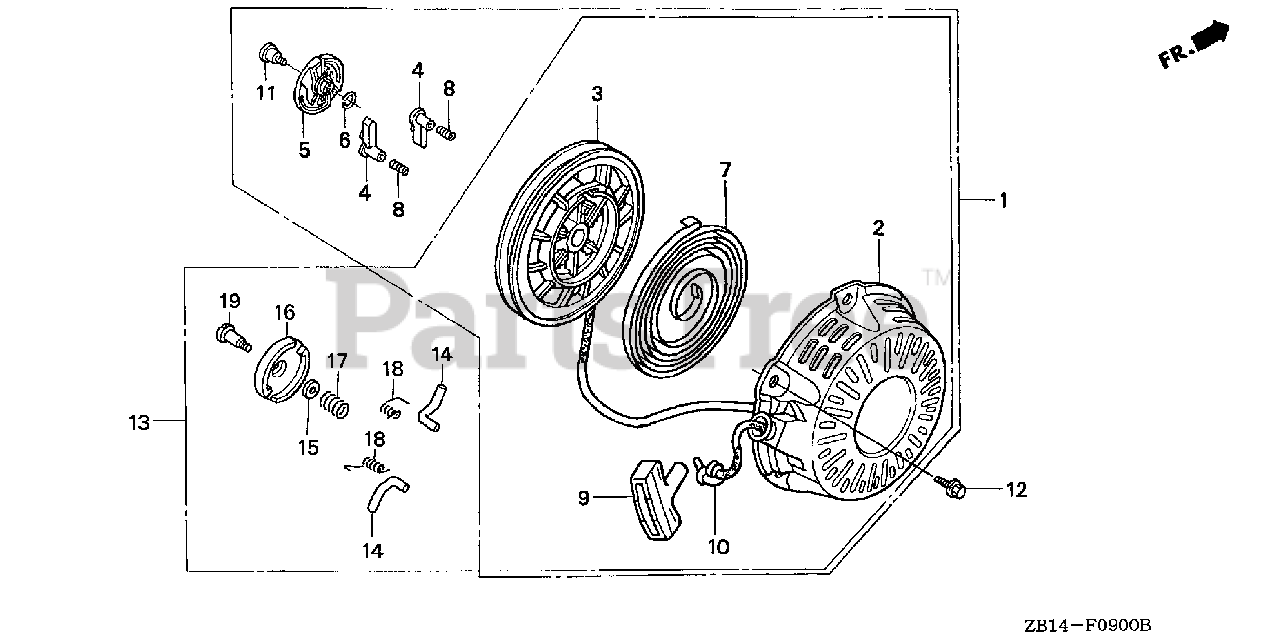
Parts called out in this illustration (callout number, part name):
1	STARTER ASSY., RECOIL *NH1* (BLACK) (ENGINE NO.)
2	CASE, RECOIL STARTER *NH1* (BLACK)
3	REEL, RECOIL STARTER (NATURAL) (ENGINE NO.)
3	REEL, RECOIL STARTER (BLACK) (ENGINE NO.)
4	RATCHET, STARTER (ENGINE NO.)
5	GUIDE, RATCHET (ENGINE NO.)
6	SPRING, FRICTION (ENGINE NO.)
7	SPRING, RECOIL STARTER
8	SPRING, RETURN (ENGINE NO.)
9	GRIP, STARTER
10	ROPE, RECOIL STARTER
11	SCREW, SETTING (ENGINE NO.)
12	BOLT, FLANGE (6X10)
13	STARTER ASSY., RECOIL *NH1* (BLACK) (ENGINE NO.)
14	RATCHET, STARTER (ENGINE NO.)
15	PLATE, FRICTION (ENGINE NO.)
16	GUIDE, RATCHET (ENGINE NO.)
17	SPRING, FRICTION (ENGINE NO.)
18	SPRING, RETURN (ENGINE NO.)
19	SCREW, SETTING (ENGINE NO.)
